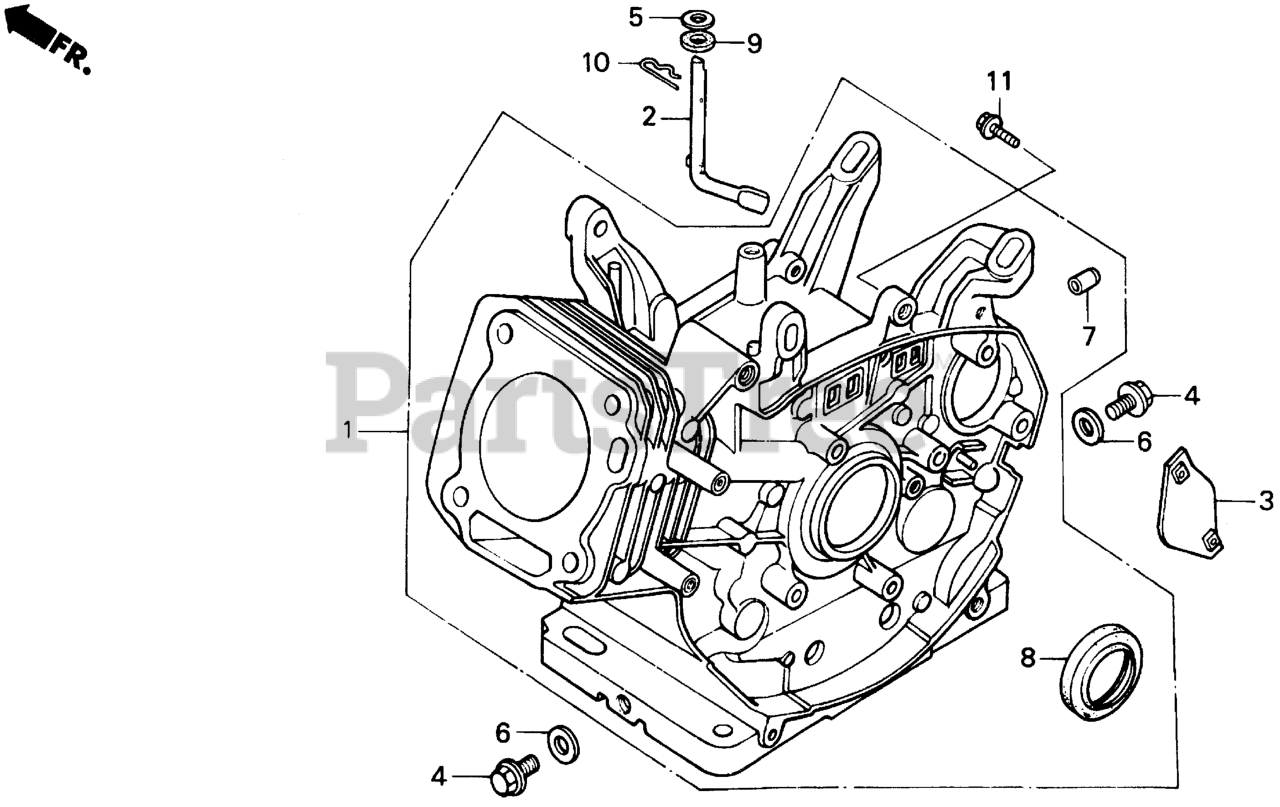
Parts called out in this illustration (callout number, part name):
1	CYLINDER ASSY.
1	CYLINDER ASSY. (SELF STARTER)
2	SHAFT, GOVERNOR ARM
3	PLATE, COVER
4	BOLT, DRAIN PLUG
5	WASHER (8.2X17X0.8)
6	WASHER, DRAIN PLUG (12MM)
7	PLUG, SEALING
8	OIL SEAL (30X46X8)
9	OIL SEAL (8X14X5)
10	PIN, LOCK (8MM)
11	BOLT, FLANGE (8X32)
